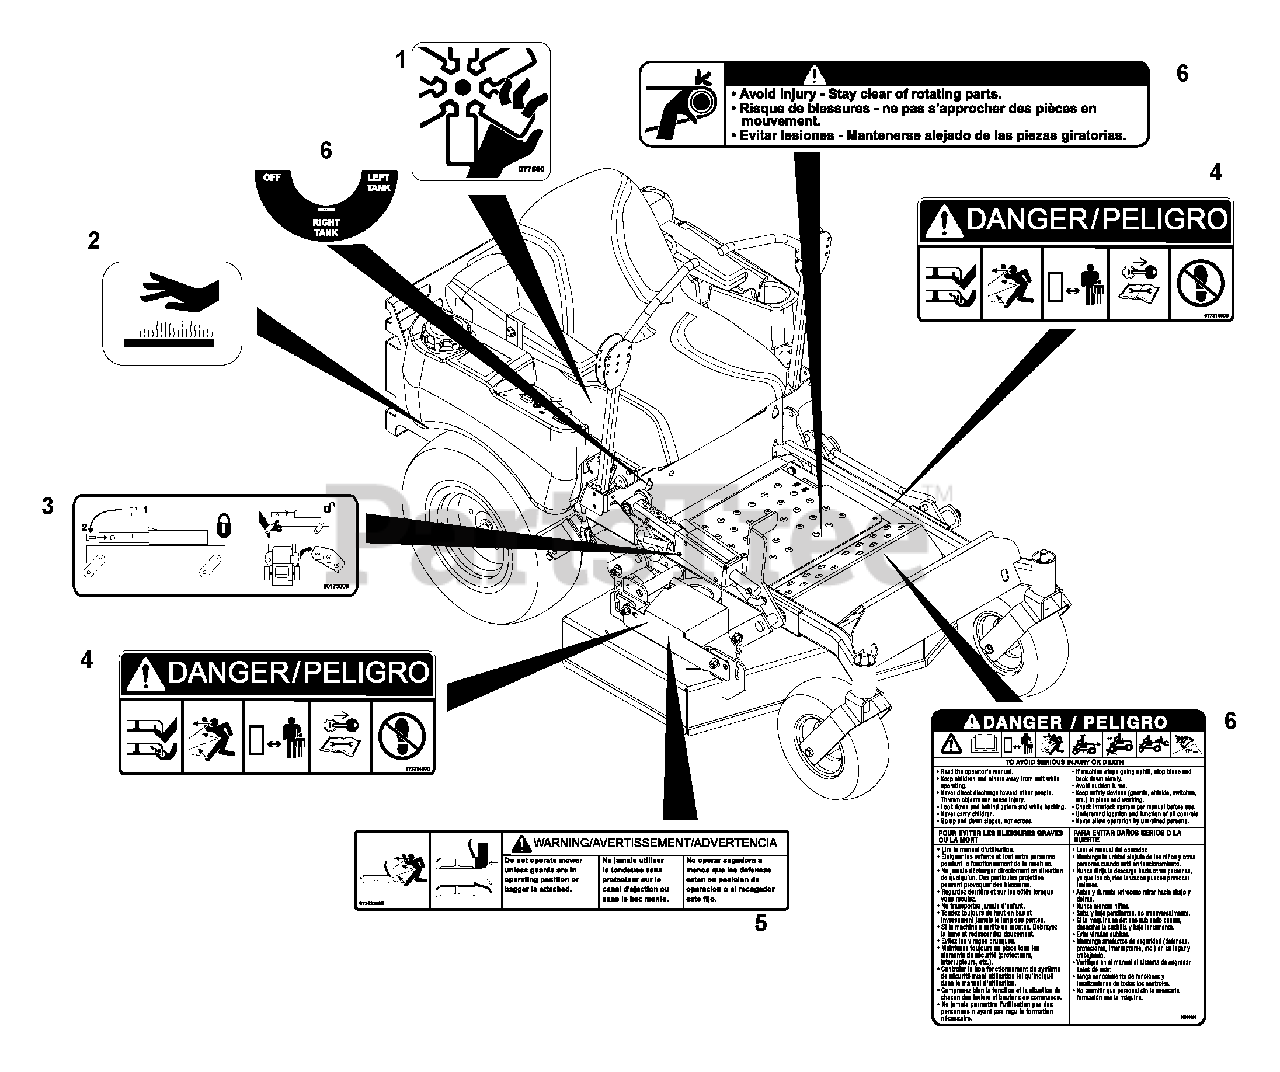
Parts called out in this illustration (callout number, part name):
1	DECAL, DANGER FAN
2	DECAL, HOT SURFACE
3	DECAL, DECK SERVICE
4	DECAL, MOWER PAN DANGER
5	DECAL, WARNING
6	SET-DECAL, COMMON DANGER/FUEL
